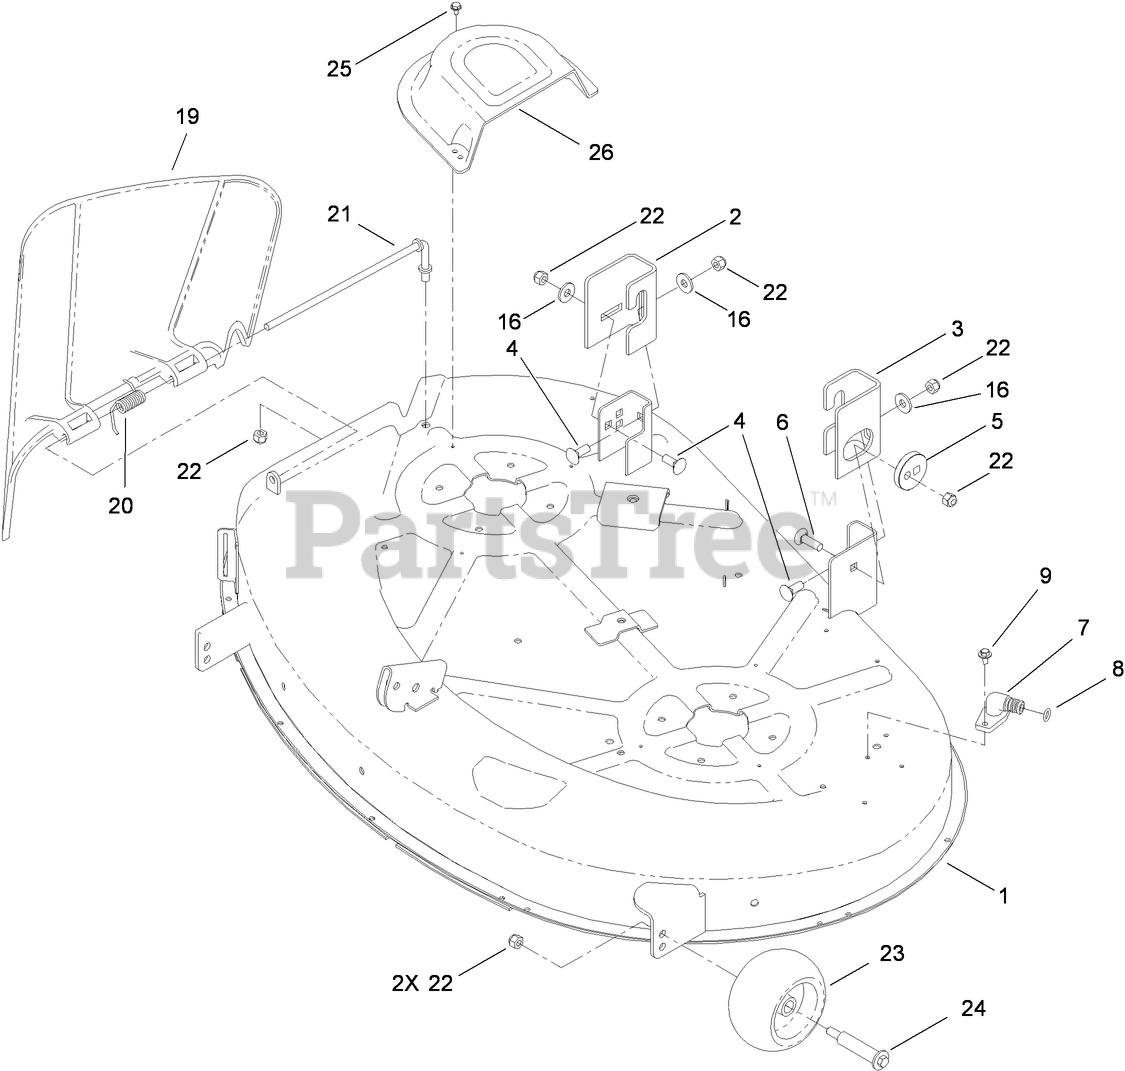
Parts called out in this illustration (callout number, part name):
2	BRACKET-HANGER, RIGHT REAR
3	BRACKET-HANGER, LEFT REAR
4	BOLT-CARR
5	ECCENTRIC
6	SCREW-CARR
8	O-RING
9	SCREW-HHFTF
16	WASHER-HARDENED
19	DEFLECTOR
20	SPRING-TORSION
21	ROD-PIVOT
22	NUT-LOCK, NI
23	ROLLER-SCALP, ANTI
24	BOLT-SHOULDER
25	SCREW-HWHTF
26	COVER-BELT
